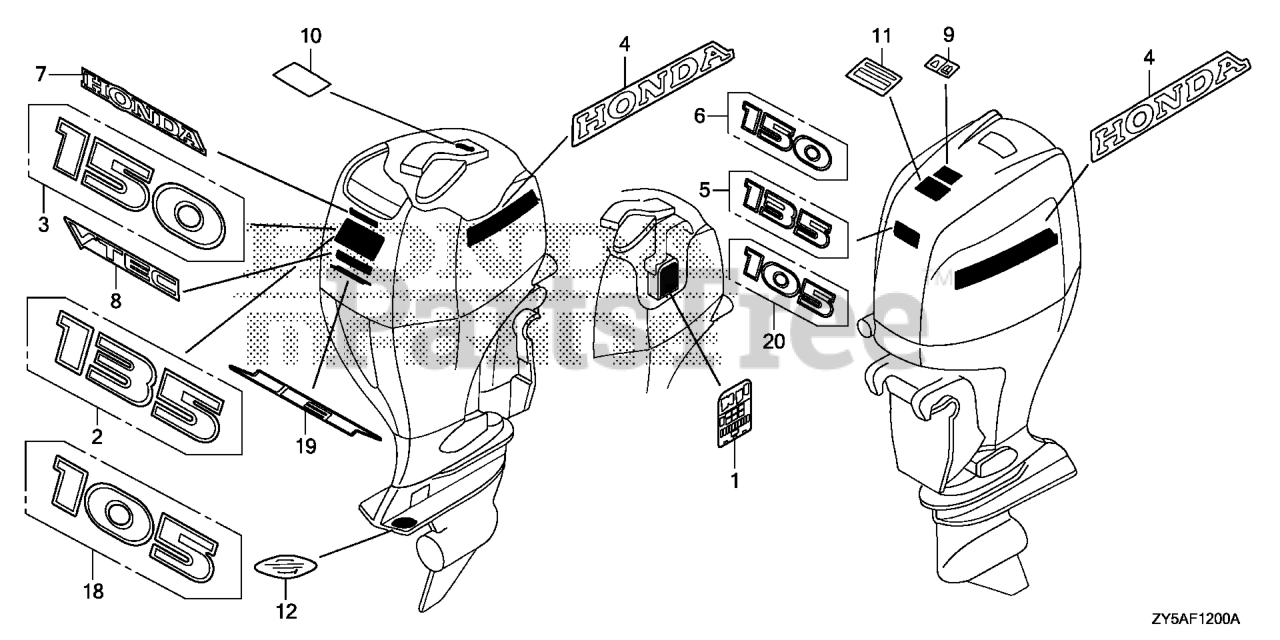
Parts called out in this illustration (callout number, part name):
1	LABEL, FUSE
2	MARK, RR. (135)
4	MARK, SIDE STRIPE
5	MARK, FR. EMBLEM (135)
7	MARK, HONDA
10	LABEL, OIL CAUTION (E)
11	LABEL, WARNING OPERATOR (ENGLISH)
12	MARK, COUNTER ROTATION
